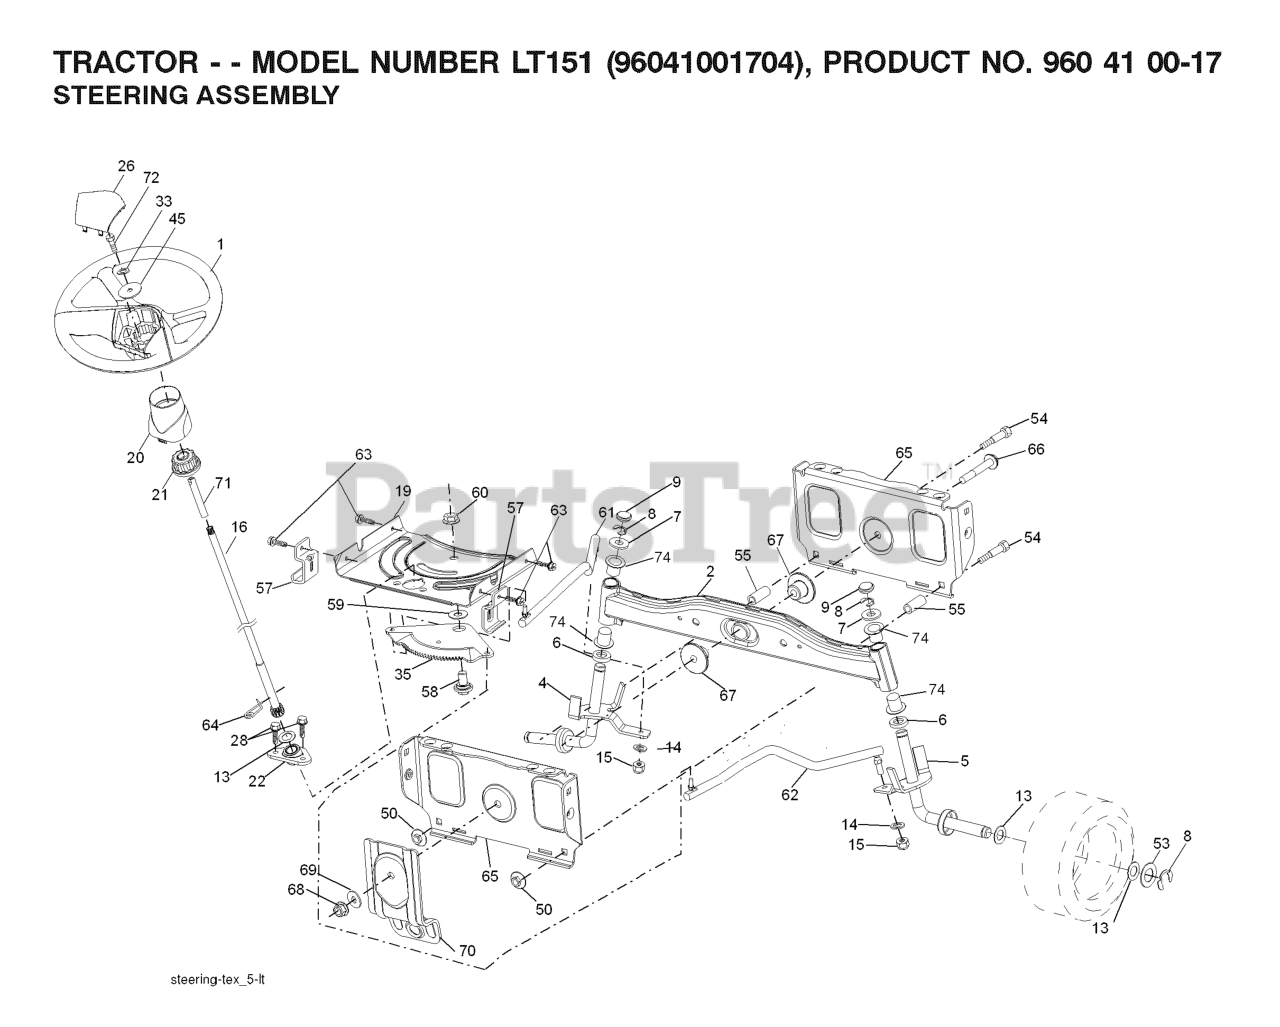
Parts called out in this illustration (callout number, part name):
1	WHEEL.STEERING.LEGEND2.GRY
2	AXLE.HALF.ASM.WELDED
4	SPINDLE.WELDED.LH.15"TEX
5	SPINDLE.WELDED.RH.15"T
6	THRUST WASHER
9	CAP.SPINDLE.BLACK
14	WASHER, LOCK 3/8
15	NUT CROWNLOCK 3/8-24
16	SHAFT STEERING
19	PLATE.STEER.DDL.NLT/NG
20	BOOT, STEERING
21	ADAPTER, WHEEL STNG..
22	BUSHING.ASM.STEERING.A
26	INSERT.CAP.STRG.WH.GRAY
28	SCREW, 3/8-16X3/4
33	WASHER.LOCK.HVY.HLCL.SPR.5/16
35	GEAR.SECTOR.PLATE.DDL.
45	WASHER.11/32
50	NUT LOCK FLG 3/8-16 UNC
53	WASHER.HARDENED
55	SPACER.BRACE.AXLE (2 2)
57	BRACKET.UPSTOP.TEX
58	BOLT.SHOULDER.SECTOR.P
59	WASHER.THURST.SECTOR.S
60	NUT FLANGE LOCK 5/8-11
61	DRAGLINK.LH.BALLSTUD.D
62	DRAGLINK.RH.BALLSTUD.D
63	SCREW
64	RETAINER.CLIP.SPRING.S
65	BRACE.AXLE.FRONT.NLT/N
66	BOLT HEX FGHD 7/16-14 X 3 SERR
67	BUSHING.PM.FRONT AXLE
68	NUT.LOCK.FLANGE.7/16
69	WASHER.1.5X.505X.118
70	BRKT.DECK.SUSPENSION.F
71	SHAFT EXTENSION STEERING
72	BOLT YT
74	BRNG T
